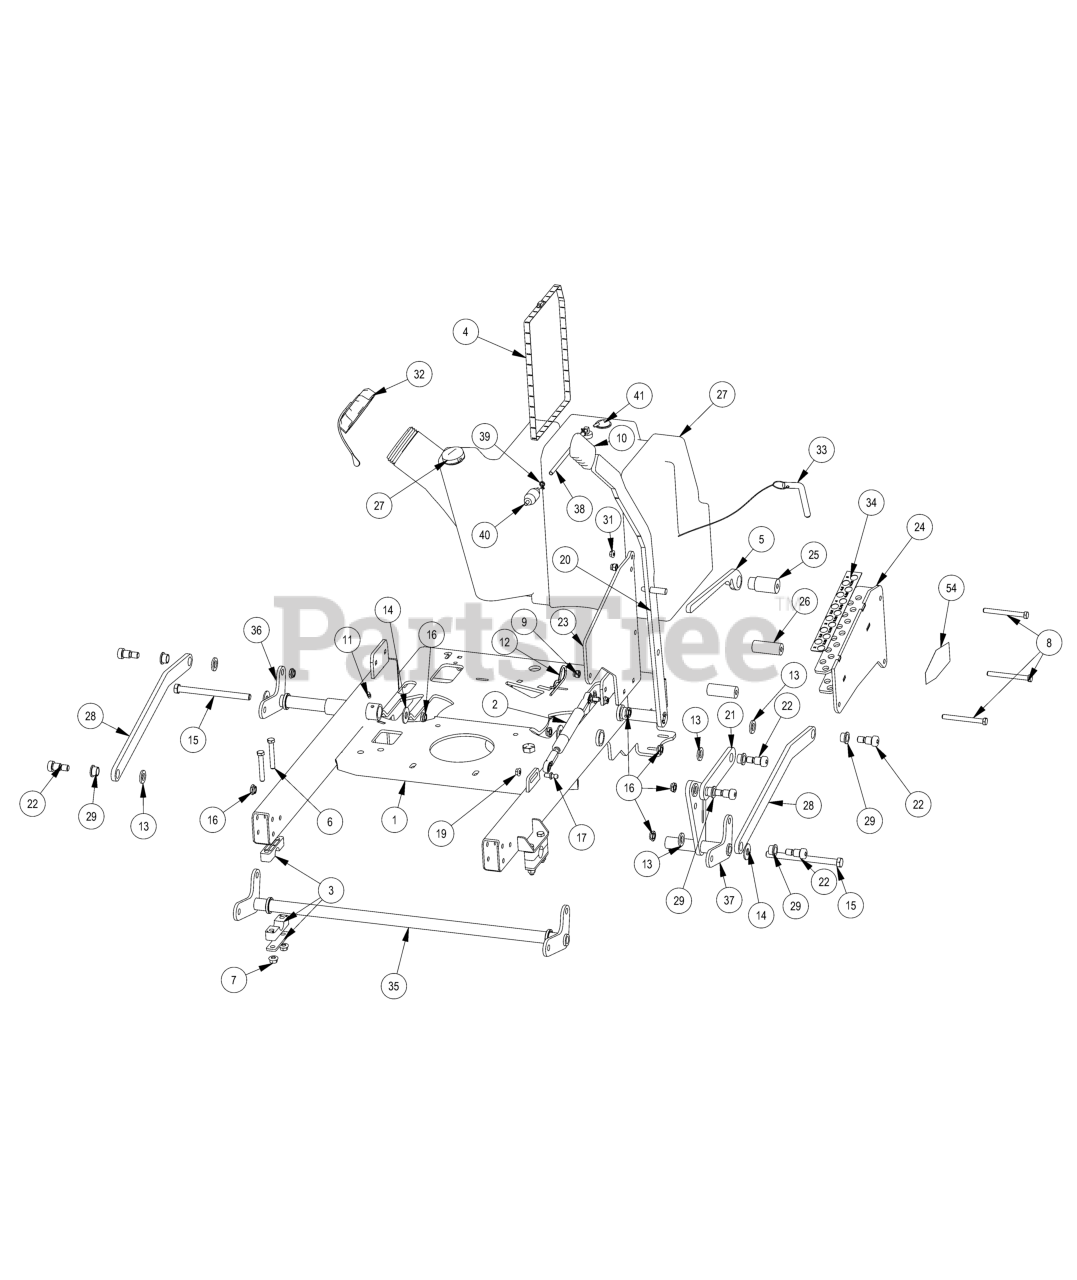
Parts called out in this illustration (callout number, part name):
1	2019 Stand On Frame
2	200 lb Gas Spring- 54" Deck outlaw
3	Pillow Block Kit
4	2019 Stand On Gas Tank Strap
5	2019 Stand On Deck Lever Lock
6	3/8-16 X 2-1/2 HEX CAP SCREW (GR.5) ZINC
7	3/8-16 NYLON INSERT FLANGE LOCKNUT (GR.F) ZINC
8	3/8-16 X 3-3/4 HEX CAP SCREW (GR.5) ZINC
9	3/8-16 NYLON INSERT LOCKNUT ZINC
10	2019 Stand On Lift Grip
11	1/4 DRIVE-TYPE STRAIGHT GREASE FITTING (NO BALL) ZINC
12	Revolt Cotter Pin for 7/8" to 1" shank
13	.635 ID X 1.120 OD X .140 THICK FLAT WASHER NYLON
14	1/2 F/W USS (1-3/8" OD) ZINCC
15	1/2-13 X 6 1/2 HEX CAP SCREW (GR.5) ZINC
16	1/2-13 NYLON INSERT JAM LOCKNUT ZINC
17	10mm Damper Ball Stud-Steering
19	5/16-18 HEX SERRATED FLANGE NUT HARD/ZINC
20	2023 Lift Lever Weldment
21	2023 lever secondary linkage
22	5/8 X 5/8 SOCKET SHOULDER BOLT ZINC YELLOW
23	2023 Stand On Inner Adjustment Plate
24	2023 Stand On Outer Adjustment Plate weldment
25	Stand On Spacer 2.5'' With shoulder
26	Stand On Spacer 2.5''
27	2023 revolt_Fuel_ tank
28	2023 Stand-on Actuator Linkage
29	.627 ID X .753 OD X .500 LGTH X 1.000 FLG OD X .094 FLG THICK
31	1/4-20 NYL INSERT FLANGE LOCKNUT ZINC
32	2023 Revolt fuel cap
33	2023 stand on Height Adj Pin
34	2023 Revolt Deck Height decal
35	2023 Stand On Front Actuator
36	2023 Stand On Actuator Rear RH
37	2023 Actuator rear_LH
38	1/4" Fuel Line Hose
39	1/4 Fuel Hose Clamp
40	27HP Kohler Fuel Filter
41	Rollover Valve W/Grommet
54	Revolt Deck Height Decal
